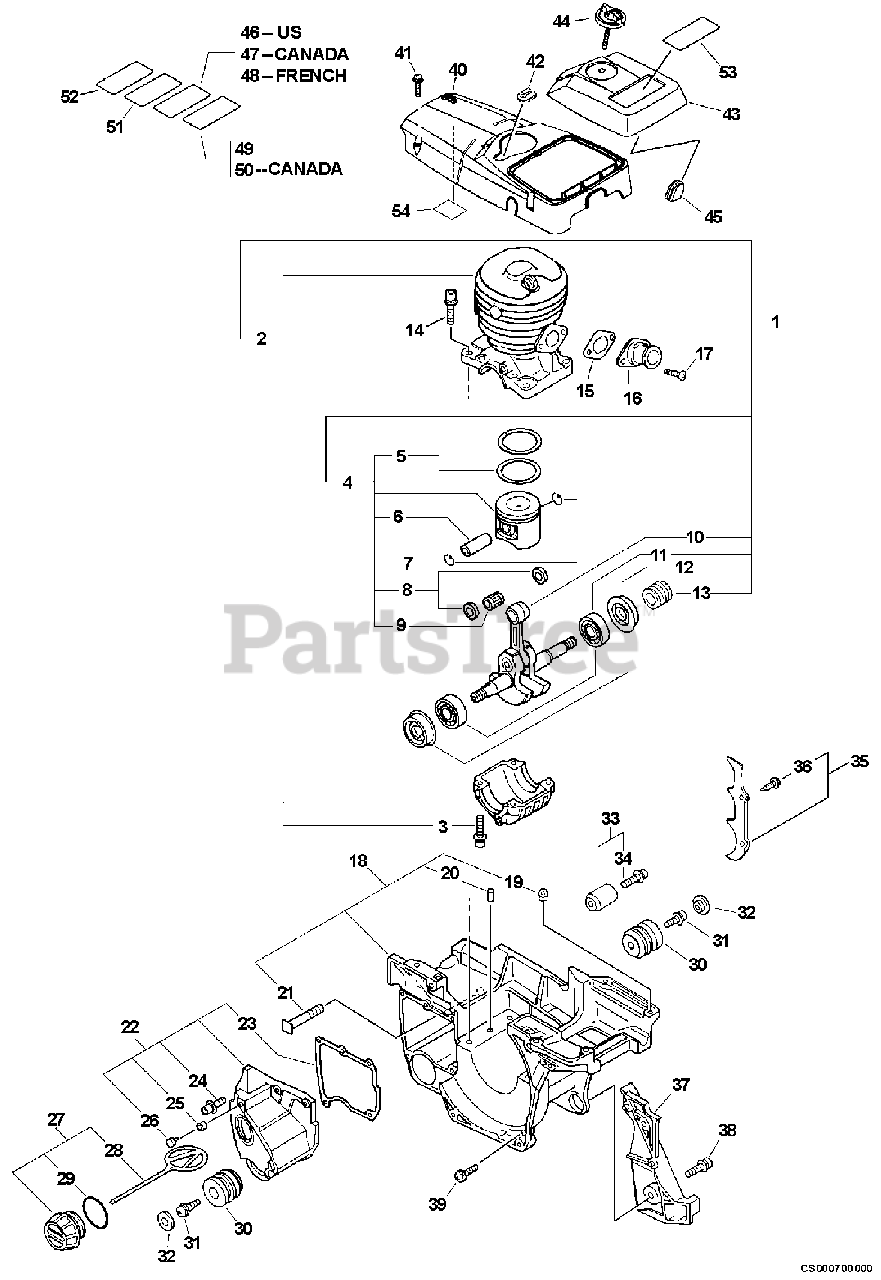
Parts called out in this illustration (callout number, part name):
1	SHORT BLOCK
2	CRANKCASE KIT
3	BOLT 5×20
4	PISTON KIT
5	RING, PISTON
6	PIN, PISTON
7	RING, SNAP
9	BEARING, NEEDLE 11
10	CRANKSHAFT ASSY
11	SEAL, OIL
12	BEARING, BALL 6202
13	GEAR, WORM
14	BOLT 5×22
15	GASKET, INTAKE
16	ADAPTOR, INTAKE
17	SCREW 5×12
18	COVER, ENGINE
19	COLLAR 5.5×6.65×5
20	PIN, LOCATING 4
21	STUD, GUIDE BAR 8
22	TANK, OIL
23	GASKET, OIL TANK
24	BOLT 4×16
25	COLLAR 5.5×6.65×5
26	VENT ASSY
27	CAP ASSY
28	CONNECTOR, CAP L= 60 MM
30	CUSHION 5
32	CAP, CUSHION
33	CHAIN CATCHER KIT
34	SCREW 5×18
35	SPIKE KIT, BUMPER
36	BOLT 5×12
37	COVER
38	SCREW 5×16
39	SCREW 5×16
40	COVER, ENGINE
42	GROMMET
43	COVER ASSY, AIR FILTER
44	THUMBSCREW
46	LABEL, UL - KICK BACK
47	LABEL, KICK BACK
48	LABEL, KICK BACK - FRENCH
49	LABEL, BAR & CHAIN
50	LABEL, BAR & CHAIN
51	LABEL, NOISE - ENGLISH/FRENCH
52	LABEL, ATTENTION - CANADA
53	LABEL, MODEL
54	SHIELD, HEAT
